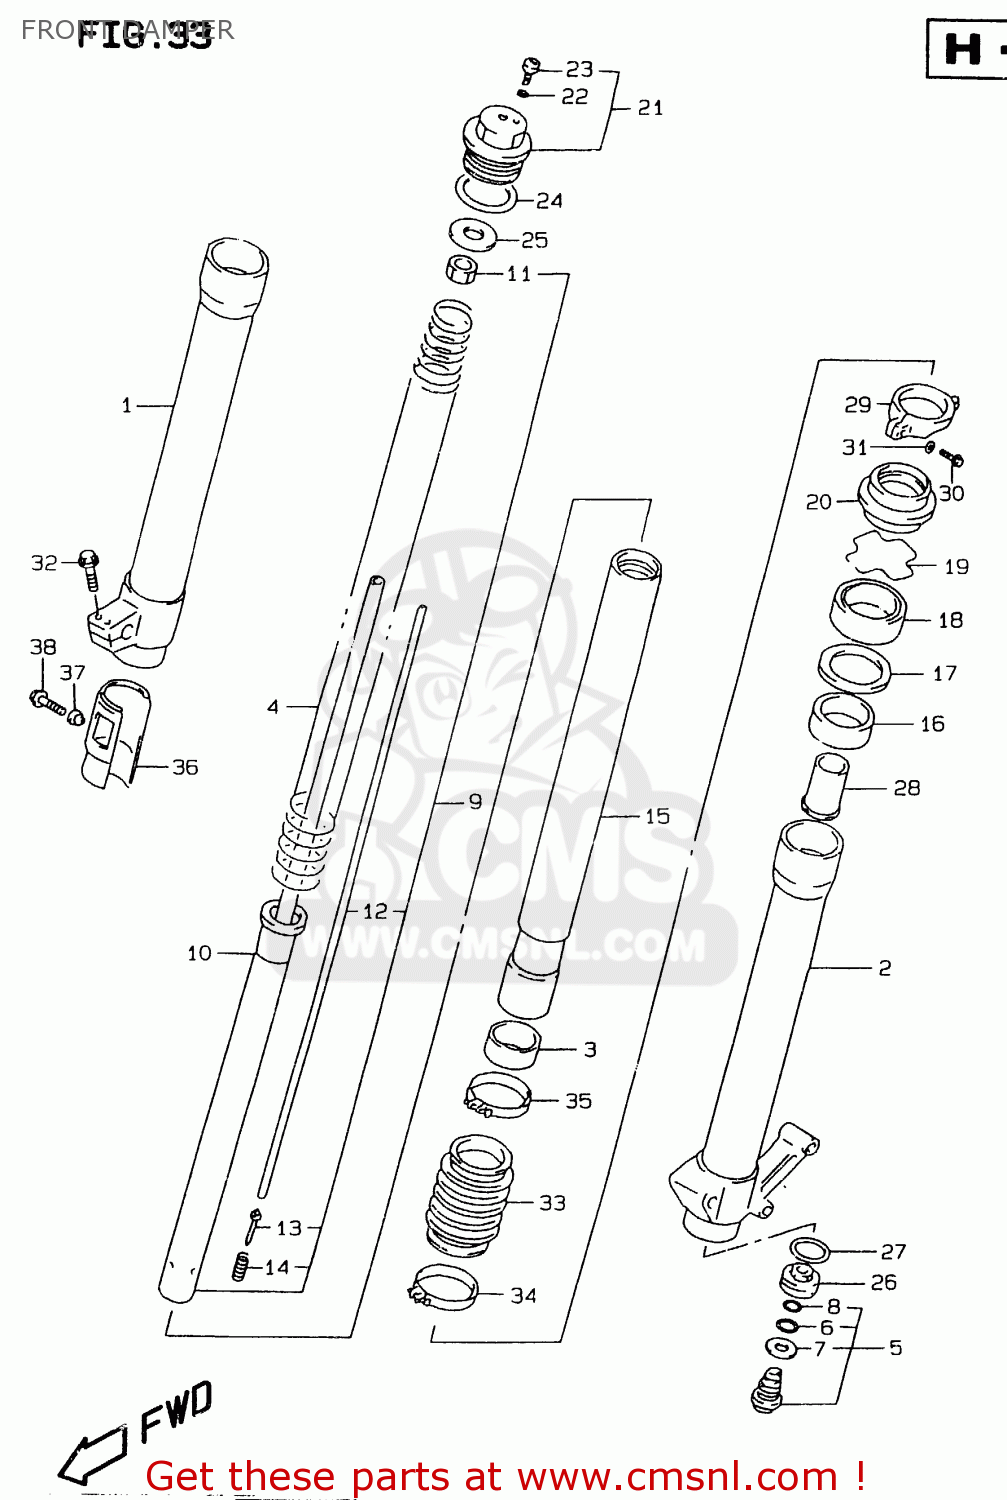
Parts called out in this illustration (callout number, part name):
1	TUBE,OUTER,RIGHT
2	TUBE,OUTER,LEFT
3	BUSH,SLIDE
4	SPRING,FR
5	BOLT,CTR
6	O RING,CTR BOLT
7	GASKET (NAS)
8	O RING,CTR BOLT UPR
9	DAMPER,FRONT
10	BUSH,SLIDE
11	NUT
12	ROD,PUSH
13	NEEDLE
14	SPRING,PUSH ROD
15	TUBE,INNER
16	BUSH,GUIDE
17	SPACER,SEAL
18	SEAL,OIL
19	RING,OIL SEAL STOPPER
20	SEAL,DUST
21	BOLT,FORK
22	O RING,PLUG
23	BOLT,PLUG
24	O RING
25	JOINT,SPRING
26	PLATE,END
27	O RING,FORK BOLT
28	PIECE,OIL LOCK
29	HOLDER
30	BOLT
31	WASHER (5.3X10X1.0)
32	BOLT
33	BOOT
34	CLAMP
35	BAND,BOOT
36	PROTECTOR,OUTER TUBE,RIGHT
37	WASHER
38	BOLT
